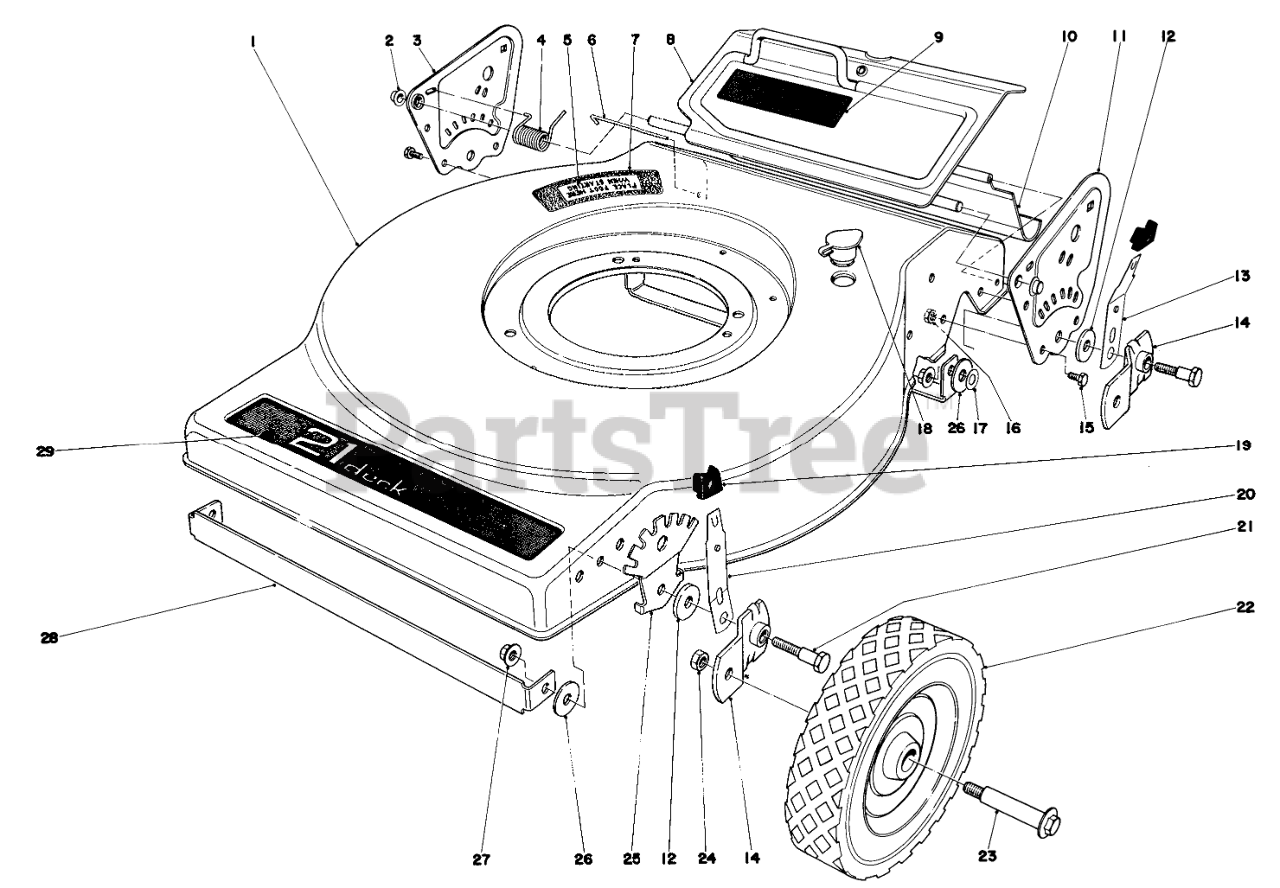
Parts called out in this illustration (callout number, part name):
1	Housing
2	RETAINER-PUSH ON
3	Side Plate R.H.
4	TORSION SPRING
5	Decal Step Pad
6	SHIELD ROD
7	PAD STEP
8	Rear Door
9	Decal Door
10	SAF SHIELD REAR
11	Side Plate L.H.
12	PIVOT WASHER
13	Spring Arm
14	PIVOT ARM ASM A
15	SCREW-HH
16	NUT-LOCK, CONE
17	WASHER-PLAIN
18	WASHOUT PLUG
19	KNOB-ARM
20	SPRING ARM ASM
21	PIVOT SCREW
22	Wheel Assembly
24	Nut
25	Quadrant
26	WASHER
28	DECK SUPPORT
29	Decal Deck
